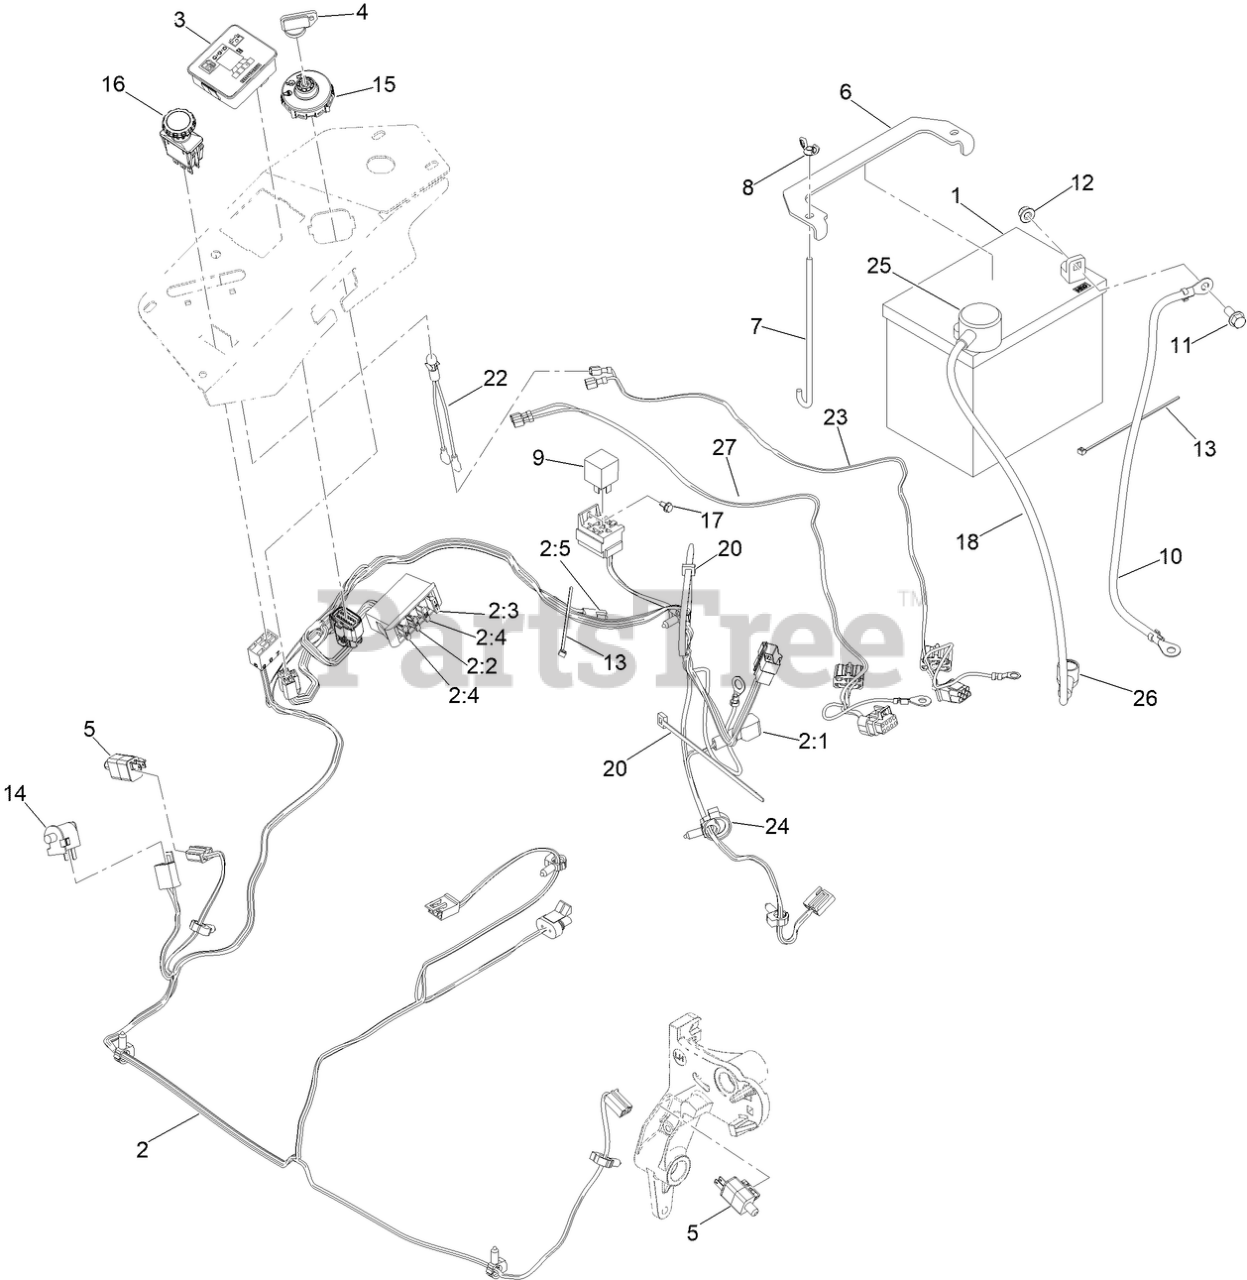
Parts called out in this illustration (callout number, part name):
1	BATTERY-DRY
2	HARNESS-WIRE, MAIN
2:2	FUSE-BLADE, 10 AMP
2:3	FUSE-BLADE, 15 AMP
2:4	FUSE-BLADE, 25 AMP
2:5	CAP-PLUG
3	FUEL/HOUR METER ASM
4	KEYS-IGNITION (SPARE PAIR)
4	KEY-IGNITION
5	SWITCH
6	STRAP-TIE DOWN, BATTERY
7	BOLT-HOLDDOWN
8	WINGNUT
10	CABLE-BATTERY, BLACK
11	SCREW-HHF
12	NUT-HF, NI
13	TIE-CABLE
14	SWITCH-BAIL
15	SWITCH-IGNITION
16	SWITCH, PTO 10A
17	SCREW-HWH
18	CABLE-BATTERY, POSITIVE
20	TIE-CABLE
22	INDICATOR-LED, RED
23	HARNESS-LIGHT, INDICATOR
24	CLAMP-HOSE
25	INSULATOR-BATTERY
26	INSULATOR-SOLENOID
27	HARNESS-JUMPER EFI
